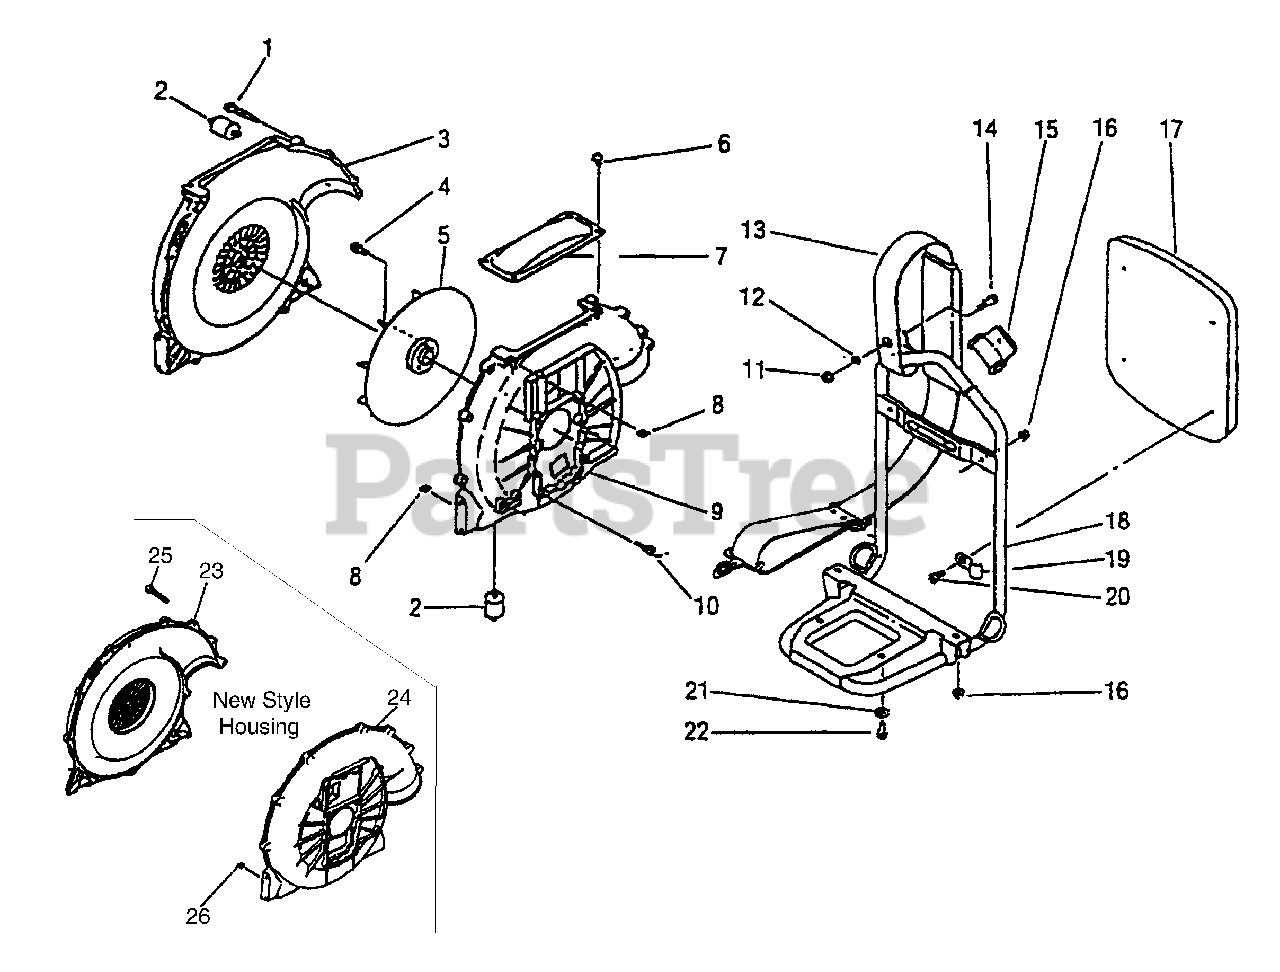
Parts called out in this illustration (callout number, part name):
1	Tapping Screw M5x30
2	Rubber AV Mount
3	Fan Housing (Old Style)
4	Pre-Coat Lock Bolt
6	Screw (M6x20)
8	Hex Nut
9	Fan Housing (Old Style)
10	Pre-Coat Lock Bolt
11	Flange Nylon Nut (M6)
12	Washer
13	Shoulder Strap
14	Truss Screw (M6x20)
15	Strap Su port
16	Flange Nut (M6)
17	Backpack Pad
18	Backpack Frame
20	Hex Bolt (M5x12)
21	Plain Washer (M6)
22	Screw (M6x10)
23	Fan Housing (New Style)
24	Fan Housing (New Style)
25	Tapping Screw
26	Hex Nut
